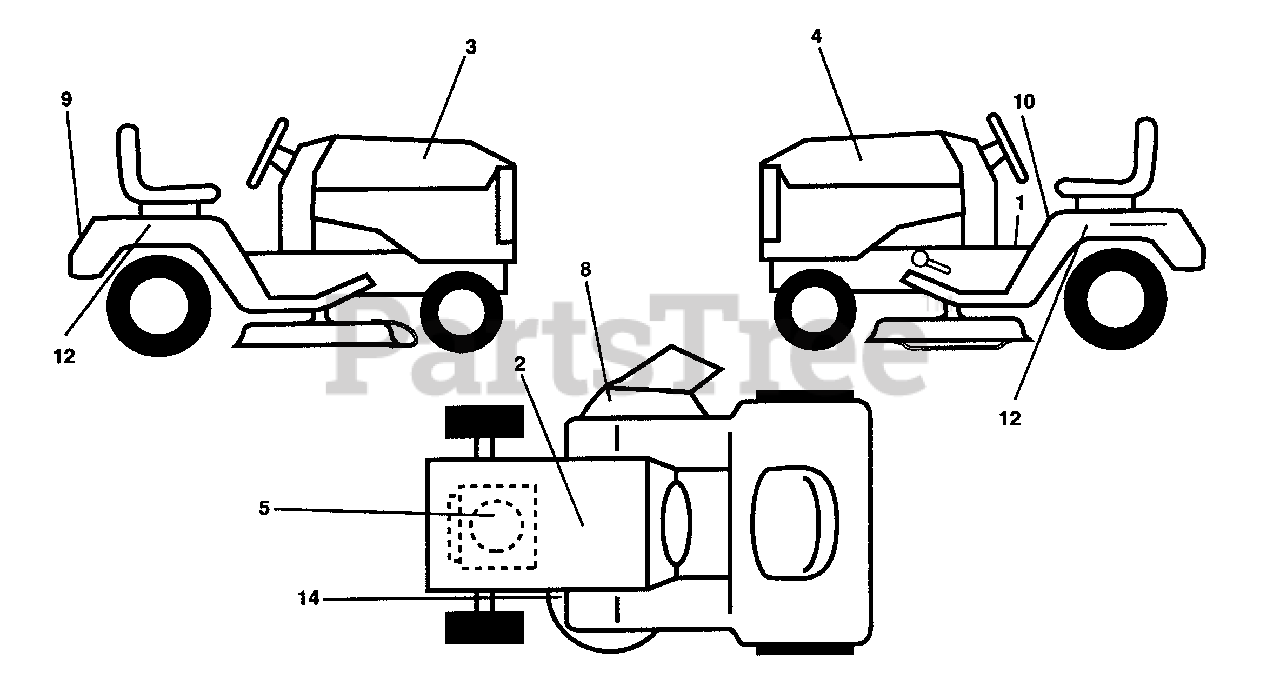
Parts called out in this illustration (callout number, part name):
1	Decal Oper. Step Thru E/F
2	Decal Battery Dan/Poi P/L Sym WPN
3	Decal Hood RH
4	Decal Hood LH
5	Decal HP Engine
8	Decal Warning Multi-Languages
9	Decal Fender Husq
10	Decal Fender Danger E/F
12	Decal Fender Auto Husq Radius
14	Decal V-Belt Schematic
